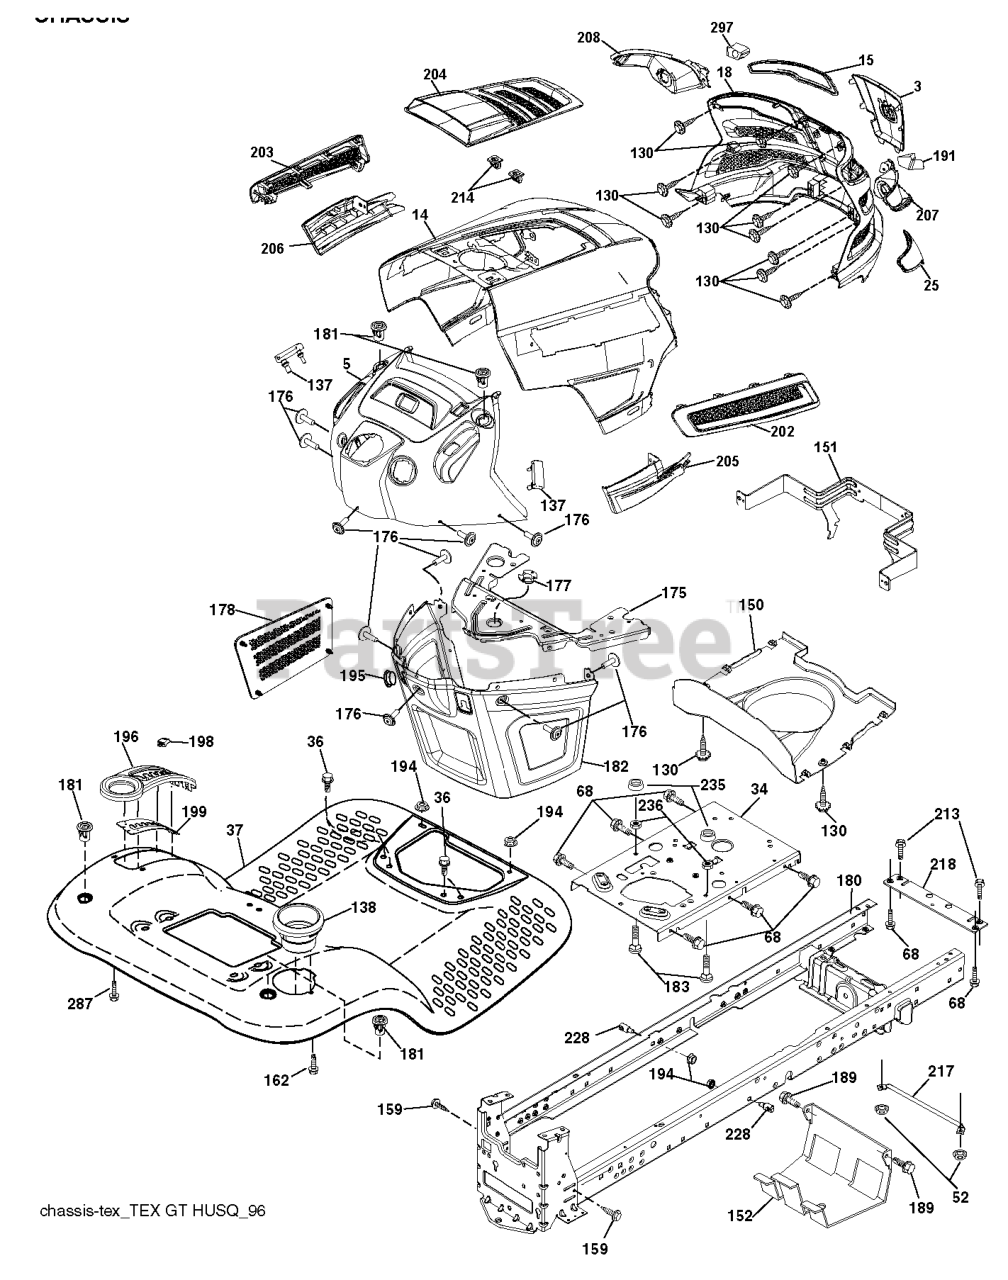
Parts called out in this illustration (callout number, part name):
3	APPLIQUE.SUBASM.GT.HUSQ.II
5	DASH.UPP.GT2.SM.MCLUTCH.CHOK
14	HOOD.ASM.HUSQVARNA.GT.TEX.ORAN
15	LENS.HEADLIGHT.LH.GTII.2011
18	GRILLE.SUBSTRATE.2011.
25	LENS.HEADLIGHT.RH.GTII.2011
34	PLATE.ENGINE.WELDED.CHASSIS
36	SCREW 5/16"
37	FENDER.TLT.PDL.CNTRL.W/CPH.ORG
52	LOCKNUT
68	Screw 5/16-18 x 1/2 Hex, Self Tapping 5/16-18 x 1/2
130	SCREW.#10 X 0.750.BOS
137	BUMPER DASH
138	CUPHOLDER.TL.TEX.418
150	AIR.DUCT.GTV.BLACK
151	BRACKET.PIVOT.HOOD.GT.HUSQ.II
152	SHIELD.BROWNING.W/TEX
159	SCREW, 3/8-16X3/4
162	SCREW.HI-LO.CONSOLE
175	PLATE.CROSSMEMBER.HUSQ
176	SCREW.#10-24X5/8.RN.QU
177	BUSHING, STEERING
178	CARGO.ASM.NET.TXGT.W/C
180	CHASSIS
181	BUSHING.MNT.FEND.CRGO.
182	DASH.LOWER.COMMON.12V.ADAPTOR
183	BOLT.5/16-18X1-1/4 FULL THD
189	SCREW
191	INSERT.REFLECTIVE.RH.HUSQ.GTII
194	NUT LOCK HEX FLANGE 5/16-18
195	PLUG.HOLE.DASH.LOWER.12V.BLK
196	CONSOLE.DECK.LIFT.TLT.GR
198	INDICATOR DECK LIFT
199	PLATE.DECK.LIFT.HUSQ.LT
202	VENT.SIDE.RH.GT.HUSQ.II.
203	VENT.SIDE.LH.GT.HUSQ.II.498
204	VENT.TOP.HUSQ.GT2
205	SIDE.TRIM.RH.GT.HUSQ.II
206	SIDE.TRIM.LH.GT.HUSQ.II.GRAY
207	BEZEL LIGHT.RH.GT.II.MYLAR
208	BEZEL LIGHT.LH.GT.II.MYLAR
213	BOLT
214	CLIP.RETAINER.TINNER.
217	ROD.PIVOT.HOOD
218	X-PIECE.HOOD.STOP.NON/
228	STUD.FASTNER.W/ANTI-ROTATE
235	SPACER FENDER
236	NUT.CENTERLOCK.5/16-
287	SCREW 1/4X20
297	INSERT.REFLECTIVE.LH.HUSQ.GTII
